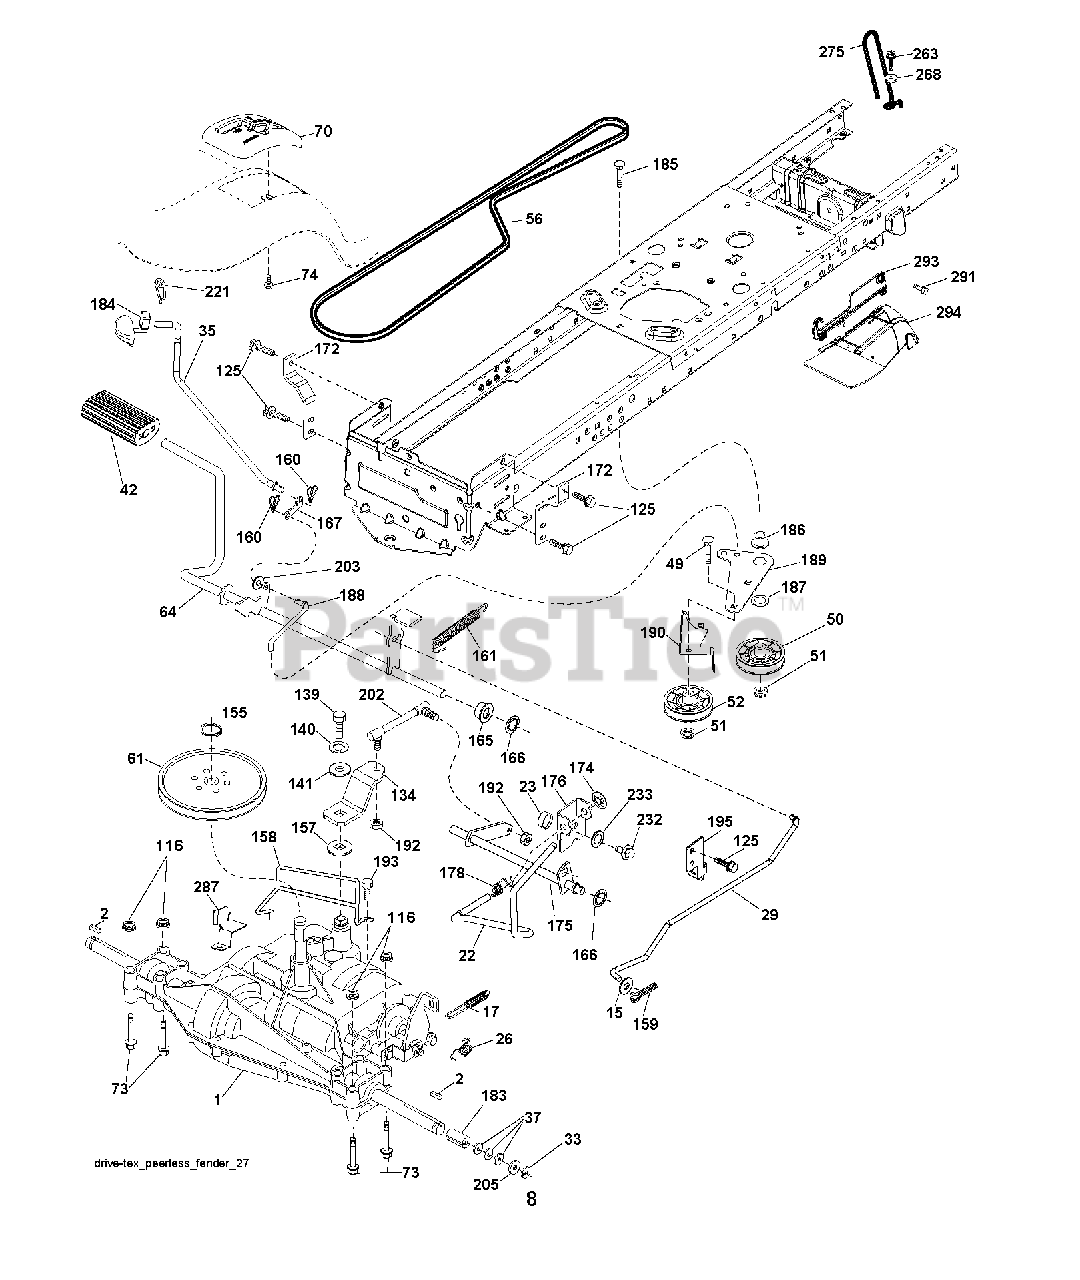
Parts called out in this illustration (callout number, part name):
2	SQUARE KEY
17	SPRING.BRAKE.PEERLESS.TEX
22	ROD.SHIFT.FENDER.TLT.2006
23	KNOB.DUCKHEAD.1/2
26	SPRING.BRAKE.RTN.GR.DR
29	ROD.BRAKE.PEERLESS
33	E-RING LT
35	ROD, BRAKE, PARK
42	PEDAL COVER T
49	BOLT
50	IDLER.FLAT.910.OFFSET
51	NUT LOCK FLG 3/8-16 UNC
52	IDLER.V-GROOVE.910.OFFSET
56	BELT, V GROUND DRIVE 95 25
64	SHAFT.ASM.PEDAL.BRAKE.
70	CONSOLE.SHIFT.
74	SCREW.HI-LO.CONSOLE
116	NUT LOCK HEX FLANGE 5/16-18
125	SCREW
134	ARM SHIFT
139	BOLT 1/4-28X3/4
140	LOCKWASHER
141	WASHER LT
155	RETAINING RING LT
157	WASH-SHFT PLT LT
158	KEEPER.PMS.18/20.D4365
159	COTTER PIN
160	RETAINER CLIP
161	SPRING, RETURN LT
165	BUSHING.SHAFT.BRAKE.HAND
166	NUT.PUSH.625
167	LATCH.BRAKE.SPRING
172	STRAP.TRQ.LH.GEAR.DRIV
174	NUT.PUSH.500.2006
175	SHAFT ASM SHIFT
176	ARM.CLEVIS.ROD.SHIFT
178	SPRING.SHIFT.GT2006
183	SPACER AXLE
184	HANDLE.PARKING.BRK.PRED.LT.RED
186	SPACER.RETAINER
187	WASHER 12/32X2X10GA
188	LINK.CLUTCH.GROUND.DRIVE
189	BELLCRANK.GROUND.DRIVE.TEX.
190	KEEPER.BELLCRANK.DRIVE
192	NUT LOCK CENTER 1/4 -28 FNTHD
193	SCREW 5/16"
195	BRKT.ROD.BRAKE.PEERLES
202	LINK.SHIFT.PMST.18"
203	WASHER
221	RETAINER.SPRING.CLIP.H
232	BOLT FIN HEX 7/16-14 X 1
233	WASHER SERRATED
263	SCREW, 3/8-16X3/4
275	WASHER
291	SHOULDER BOLT 5/16-18TT
